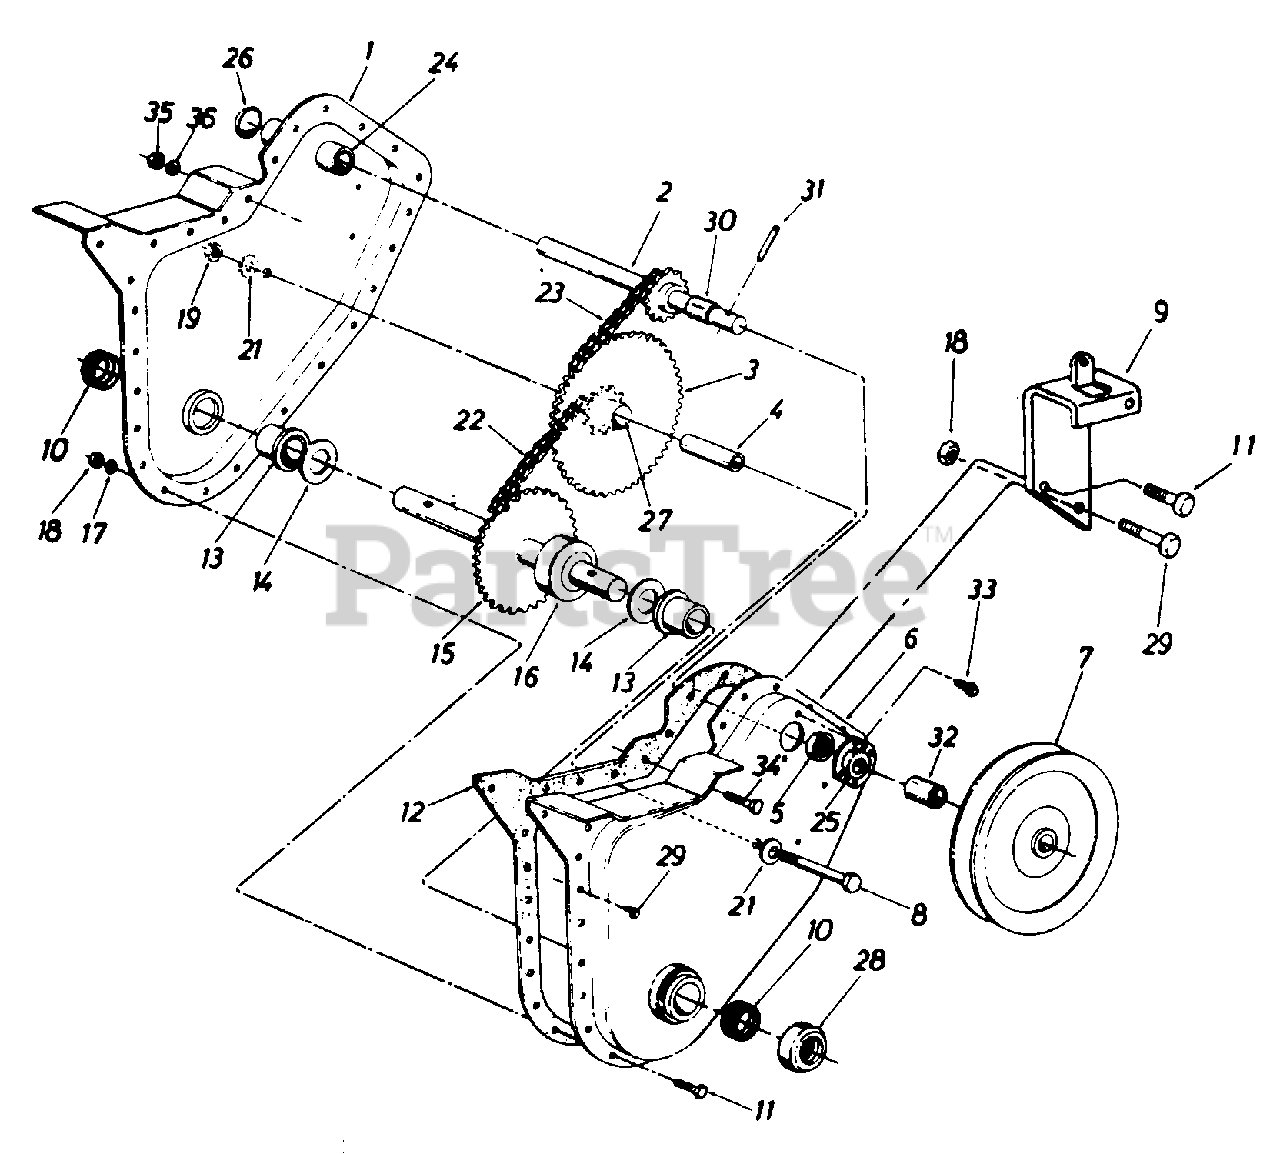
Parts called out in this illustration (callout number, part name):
1	Chain Case Ass'y.-R.H.
2	Input Shaft Ass'y.
3	Hub and Sprocket Ass'y.
4	Bearing Inner Race
5	Ball Bearing
6	Chain Case Ass'y.-L.H.
7	Pulley-Chain Case
8	Hex Bolt 3/8-24 x 2.5"
9	Fuel Tank Brkt
11	Hex Bolt 1/4-28 x .625"
12	Gasket
13	Flange Brg. .879" I.D.
14	Fl-Wash. .88" I.D. x 1.5"
15	Tine Shaft Ass'y.
16	Spacer 718" I.D.
17	L-Wash. 1/4" I.D.
18	Hex Nut 1/4-28 Thd.
19	Hex Ins. L-Nut 3/8-24 Thd.
21	Bell-Wash. .406" I.D.
22	Chain #420 1/2" Pitch 38 Links
23	Chain #35 .375" Pitch 50 Links
24	Bearing .62" I.D. x .813
25	Bearing Housing
26	Expansion Plug 13/16" Dia.
27	Bearing
28	Dust Cap
29	Hex Wash. Hd. Self-Tap Scr. 1/4-20 x .50" Lg.
30	Spacer .63" I.D. x .77" O.D. x .38" Lg.
31	Spring Pin Spiral 1/4" Dia. x 1-1/2" Lg.
32	Spacer .647 x 1.25
33	Hex Wash. Hd. Self-Tap Scr. 1/4-20 x .38" Lg.
34	Hex Bolt 5/16-18 x .75"
35	Hex Nut 5/16-18 Thd.
36	L-Wash. 5/16" I.D.
